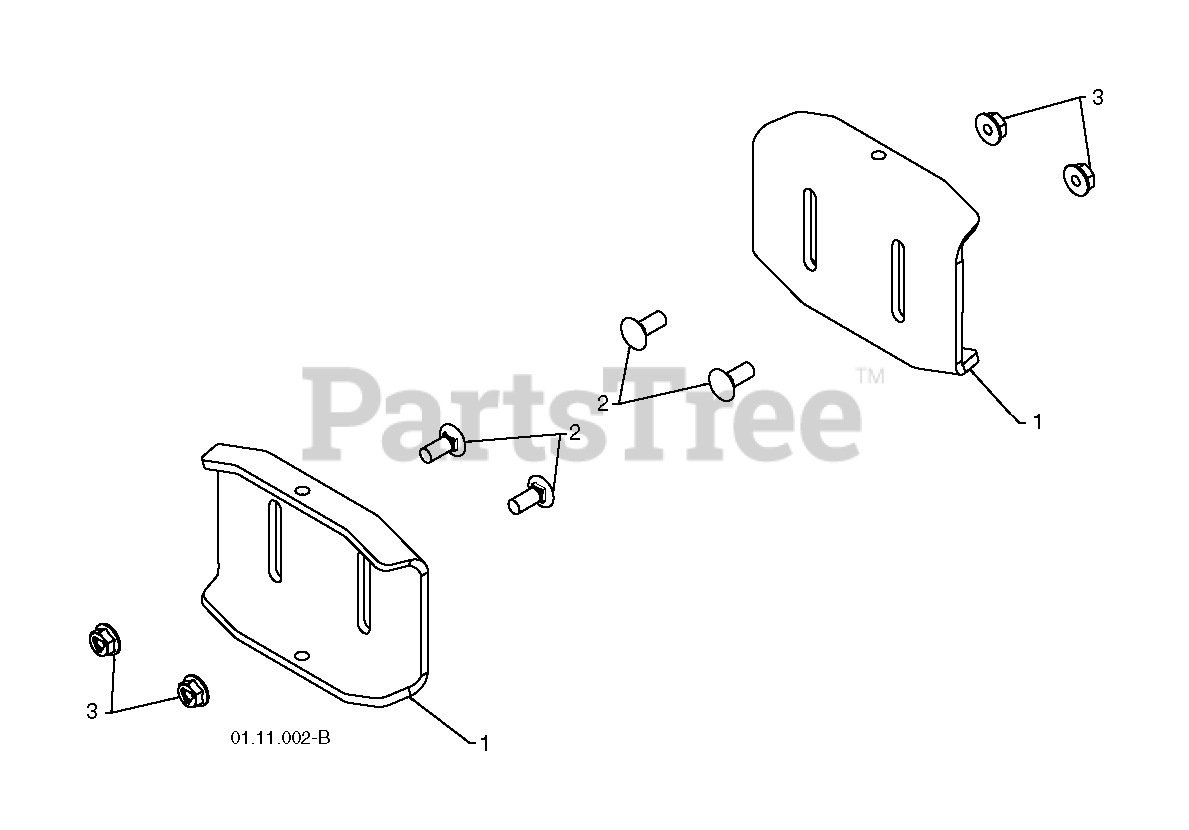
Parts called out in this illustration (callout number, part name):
1	PLATE.SKID.HEAVYDUTY.BLACK
2	BOLT
3	NUT.LOCK.5/16-18
